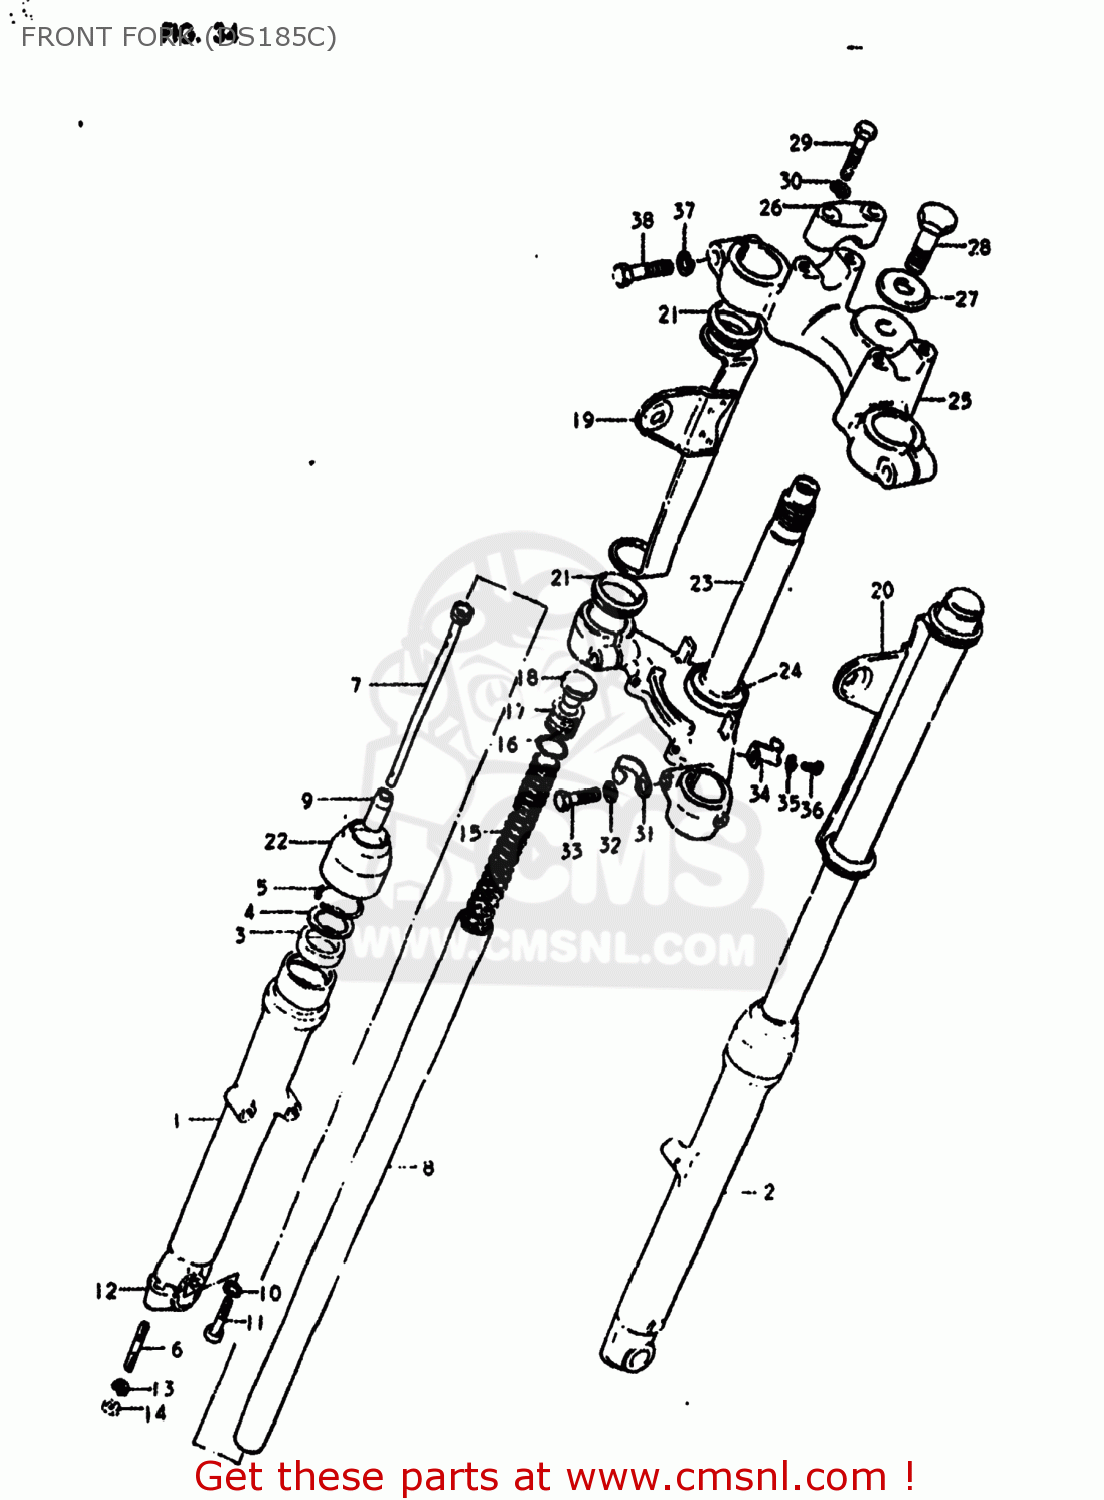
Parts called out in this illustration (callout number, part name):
0	DAMPER SET
1	TUBE,FORK,OUTER,RIGHT
2	TUBE,OUTER,LEFT
3	OIL SEAL,FRONT FORK
4	WASHER,FRONT FORK
5	RING,SNAP
6	STUD 8X30
7	CYLINDER,FRONT FORK
8	TUBE,FORK,INNER
9	PIECE,OIL LOCK
10	GASKET (NAS)
11	BOLT,FORK CYLINDER(10X25)
12	HOLDER,AXLE
13	LOCK WASHER
14	NUT (8MM)
15	SPRING
16	O RING
17	CAP
18	CAP,FR FORK
19	BRACKET,HEADLAMP HOUSING
20	BRACKET,HEADLAMP,LEFT
21	GASKET (NAS)
22	SEAL,DUST
23	STEM,STEERING
24	RACE,STEERING OUTER LWR
25	HEAD,STEERING STEM
26	HOLDER,HANDLE(BLACK)
27	WASHER,STEM HEAD
28	BOLT,FR FORK(10X33)
29	BOLT
30	LOCK WASHER
31	CLIP
32	WASHER,LOCK 12
33	BOLT,FR FORK LWR(12X33)
34	CLIP,BRAKE CABLE
35	LOCK WASHER
36	SCREW
37	LOCK WASHER
38	BOLT,FORK INNER TUBE F
